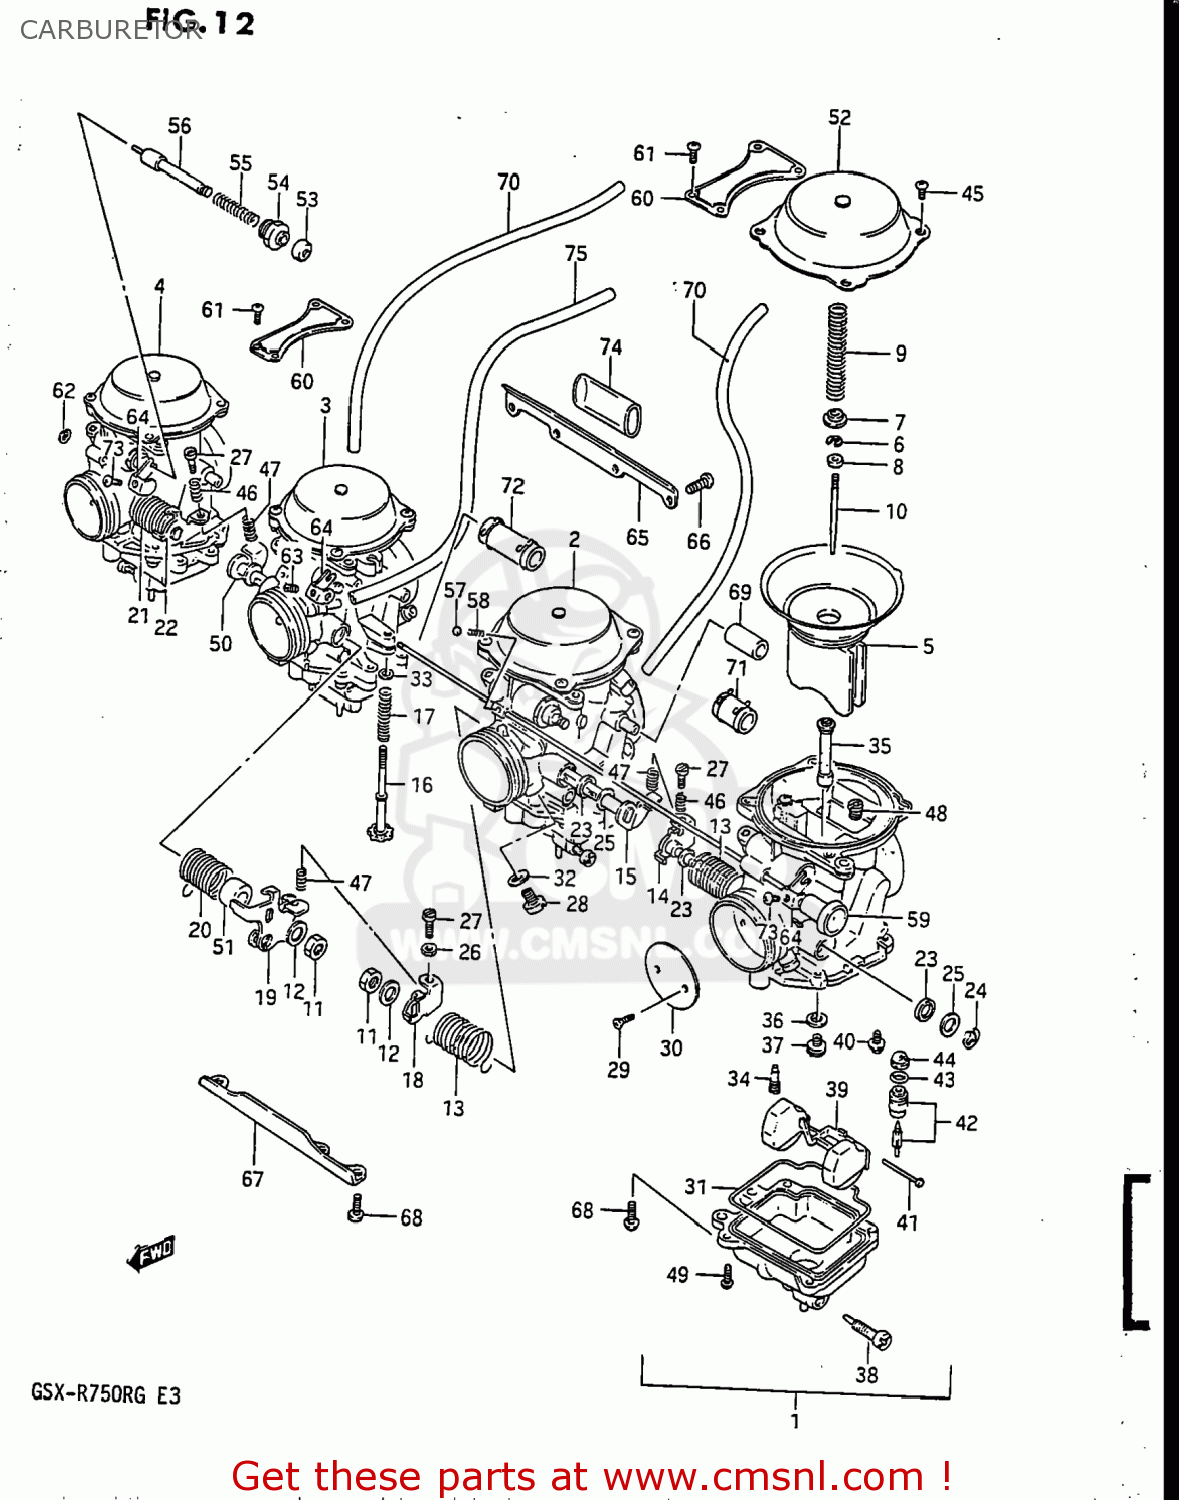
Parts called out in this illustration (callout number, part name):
1	CARBURETOR ASSEMBLY
2	CARBURETOR ASSEMBLY
3	CARBURETOR ASSEMBLY
4	CARBURETOR ASSEMBLY
5	DIAPHRAGM ASSY
6	CAP,LEVER
7	RING
8	RING
9	SPRING
10	NEEDLE,JET
11	NUT
12	WASHER
13	SPRING
14	SHAFT ASSEMBLY
15	SHAFT ASSEMBLY
16	SCREW
17	SPRING
18	LEVER
19	LEVER ASSEMBLY
20	SPRING
21	SPRING
22	SHAFT ASSEMBLY
23	SEAL
24	E RING
25	GASKET,THROTTLE SHAFT (NAS)
26	NUT,THROTTLE ROD
27	SCREW
28	SCREW
29	SCREW
30	VALVE,THROTTLE
31	O RING,FLOAT CHAMBER
32	WASHER
33	WASHER
34	JET,PILOT(32.5)
35	JET,NEEDLE(P-8)
36	WASHER,NEEDLE NOZZLE
37	JET,MAIN(117.5)
38	SCREW
39	FLOAT
40	SCREW
41	PIN,FLOAT
42	VALVE ASSY,NEEDLE
43	O RING
44	FILTER
45	SCREW
46	SPRING
47	SPRING,THROTTLE SCREW
48	JET
49	SCREW
50	SHAFT ASSEMBLY
51	RING
52	COVER,DIAPHRAGM
53	CAP,STARTER VALVE
54	GUIDE SCREW,PLUNGER
55	SPRING
56	PLUNGER ASSY
57	BALL,CARBURETOR
58	SPRING
59	SHAFT ASSEMBLY
60	PLATE
61	SCREW
62	E-RING
63	SCREW
64	LEVER
65	PLATE
66	SCREW
67	PLATE
68	SCREW
69	HOSE,CARBURETOR
70	HOSE
71	HOSE SET (3X5X18)
72	HOSE ASSY
73	SCREW
74	HOSE
75	HOSE
